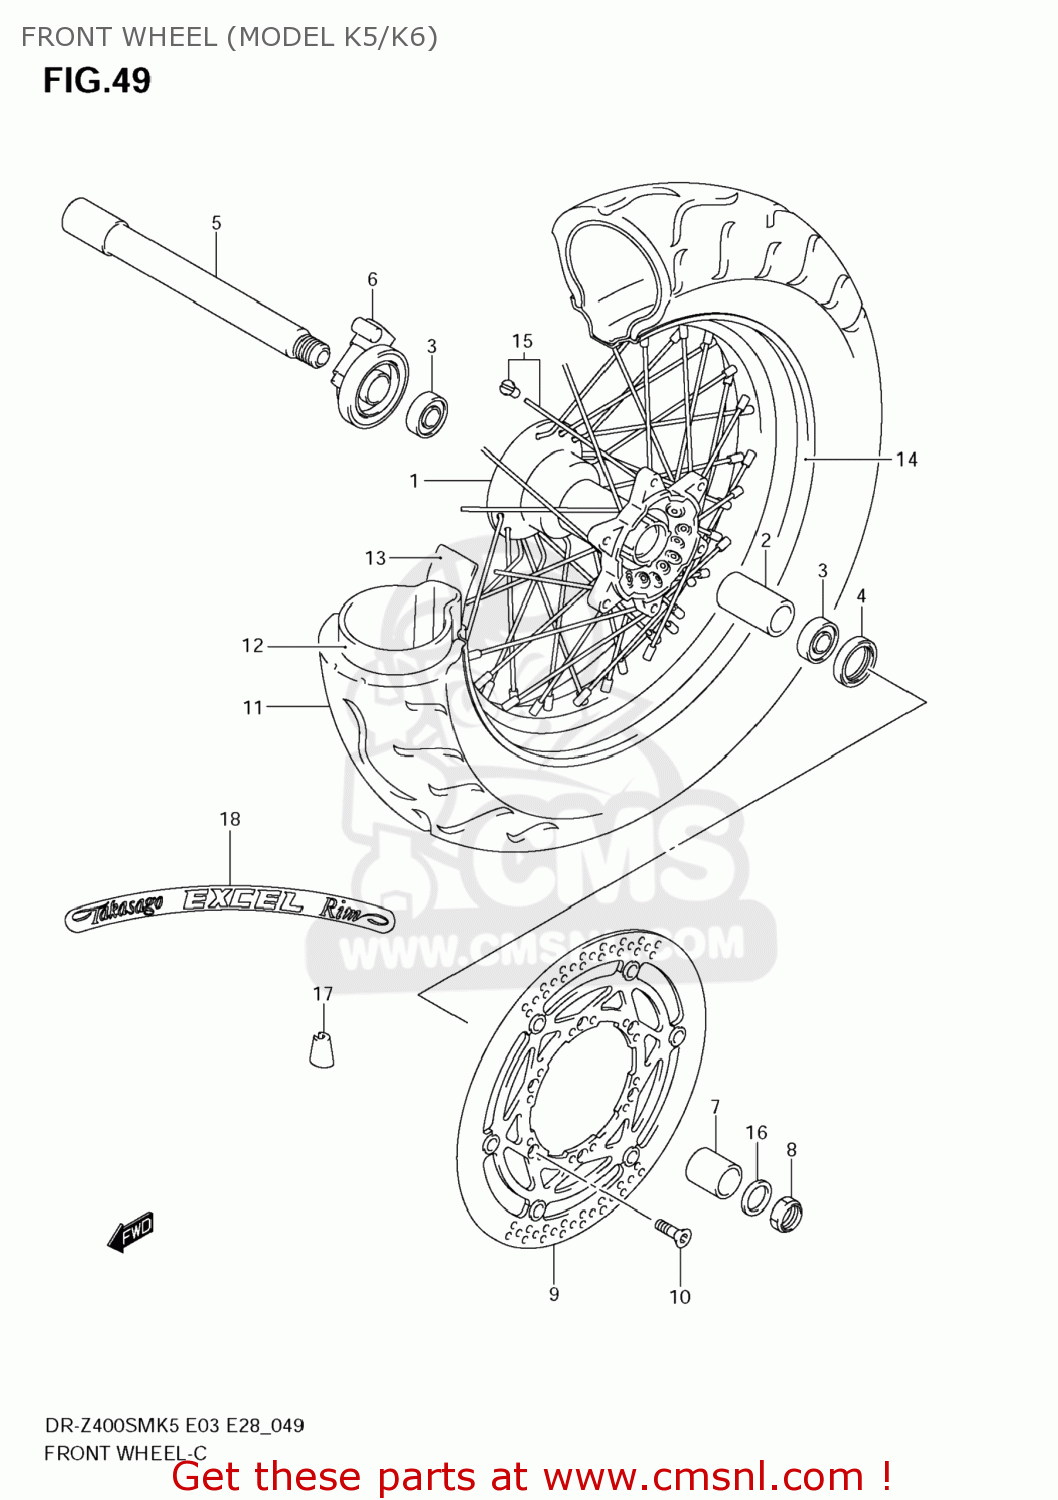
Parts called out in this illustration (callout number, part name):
1	HUB,FR WHEEL
2	SPACER,FR HUB BEARING
3	BEARING
4	SEAL,OIL(25X37X6)
5	AXLE,FR
6	BOX ASSY,SPEEDOMETER GEAR
7	SPACER,FR AXLE,L
8	NUT
9	DISC,FR BRAKE
10	SCREW(6X18)
11	TIRE,FR(120/70R17M/C 58H)
12	TUBE ASSY,WHEEL INNER
13	PROTECTOR,WHL INR TUBE
14	RIM,FR WHEEL(17XMT3.50 AL)
15	SPOKE SET,FR WHEEL
16	WASHER(18X26X2.8)
17	BALANCER,WHEEL(20G)
18	EMBLEM,EXCEL(8 PIECES SET)
